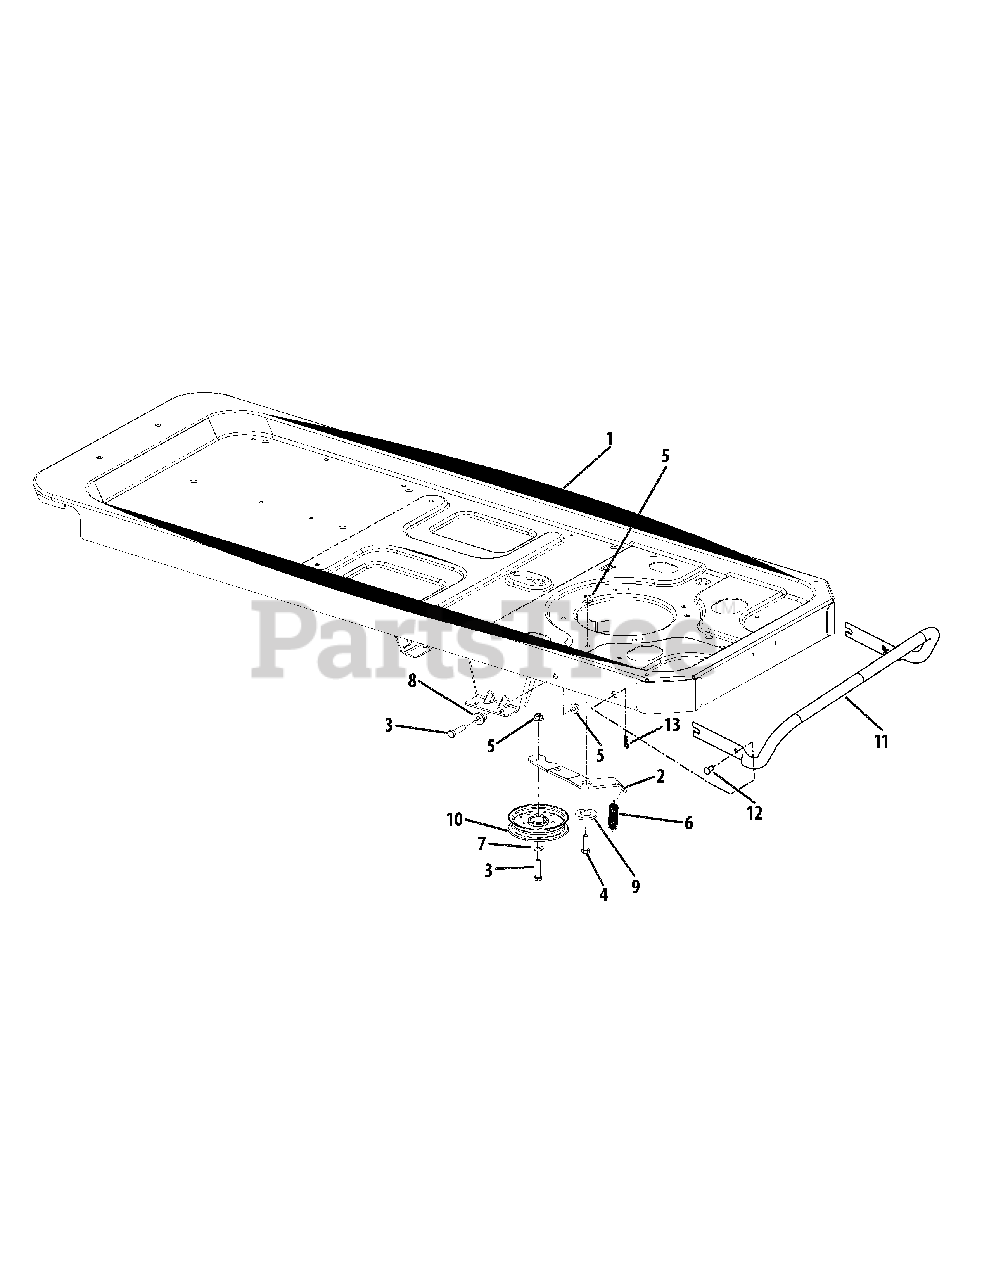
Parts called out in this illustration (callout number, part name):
3	Hex Cap Screw,3/8-16 x 1.5
4	Hex Cap Screw, 3/8-16 x 1.25
5	Hex Insert Flangelock Nut, 3/8 -16
6	Extension Spring, .75 x 5.06
7	Flat Washer, .408 x .875 x .059
8	Shoulder Spacer, .39 x 1.0 x .7
9	Shoulder Spacer, .884 x .19
10	Idler Pulley, 4.25 Dia.
13	Cotter Pin, .080 x 1.5625
